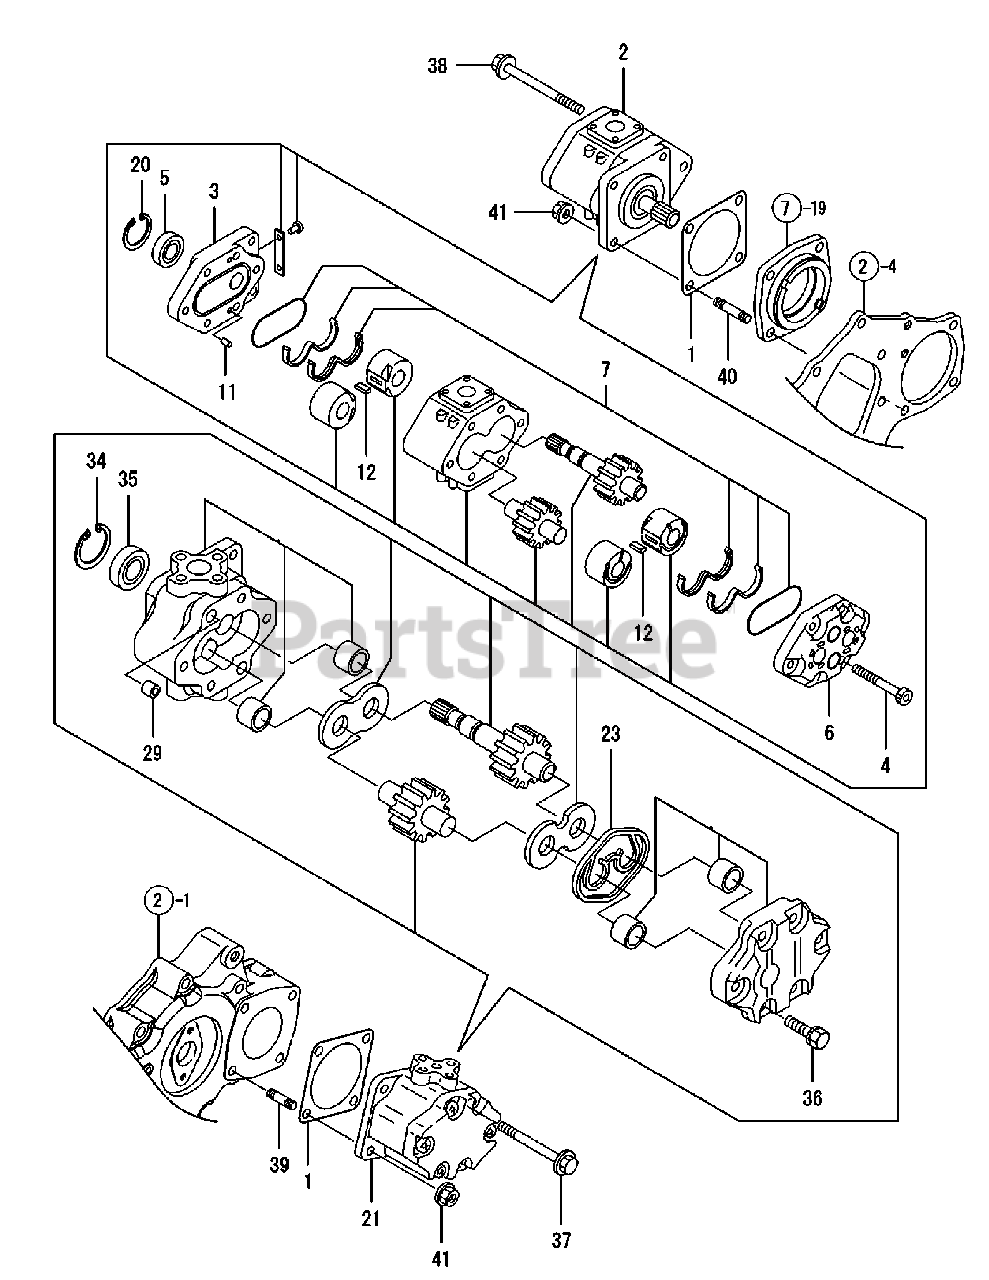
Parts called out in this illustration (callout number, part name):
4	BOLT M 8X 83.5
11	PARALLEL PIN 6X12
21	PUMP, HYDRAULIC
35	SEAL TC15 32 07, OIL
37	BOLT M 8X 80 PLATED
38	BOLT M 8X120 PLATED
39	STUD M 8X 22 PLATED
40	STUD M 8X 40 PLATED
